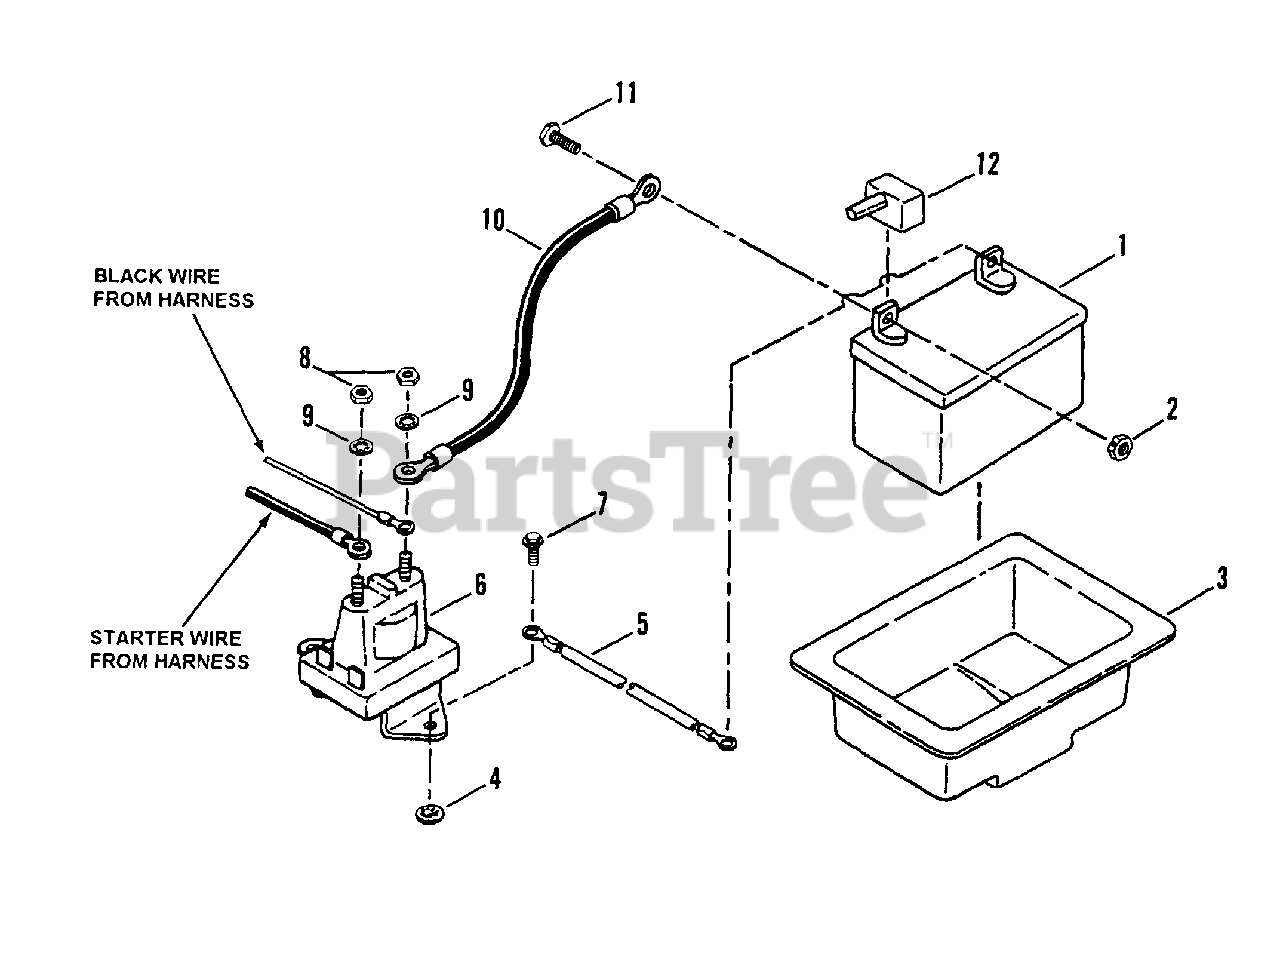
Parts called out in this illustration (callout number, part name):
1	KIT, Battery
2	NUT, 1/4-20 Hex Center Lock
3	TRAY, Battery
4	RETAINER, Screw
5	CABLE, Ground (Black)
6	SOLENOID
7	SCREW, 1/4-20 x 1/2" Self-Tapping
8	NUT, 1/4-20 Hex Jam
9	WASHER, 1/4 Internal Tooth Lock
10	CABLE, Positive (Red)
11	SCREW, 1/4-20 x 5/8" Hex Head Cap
12	COVER, Positive Terminal
